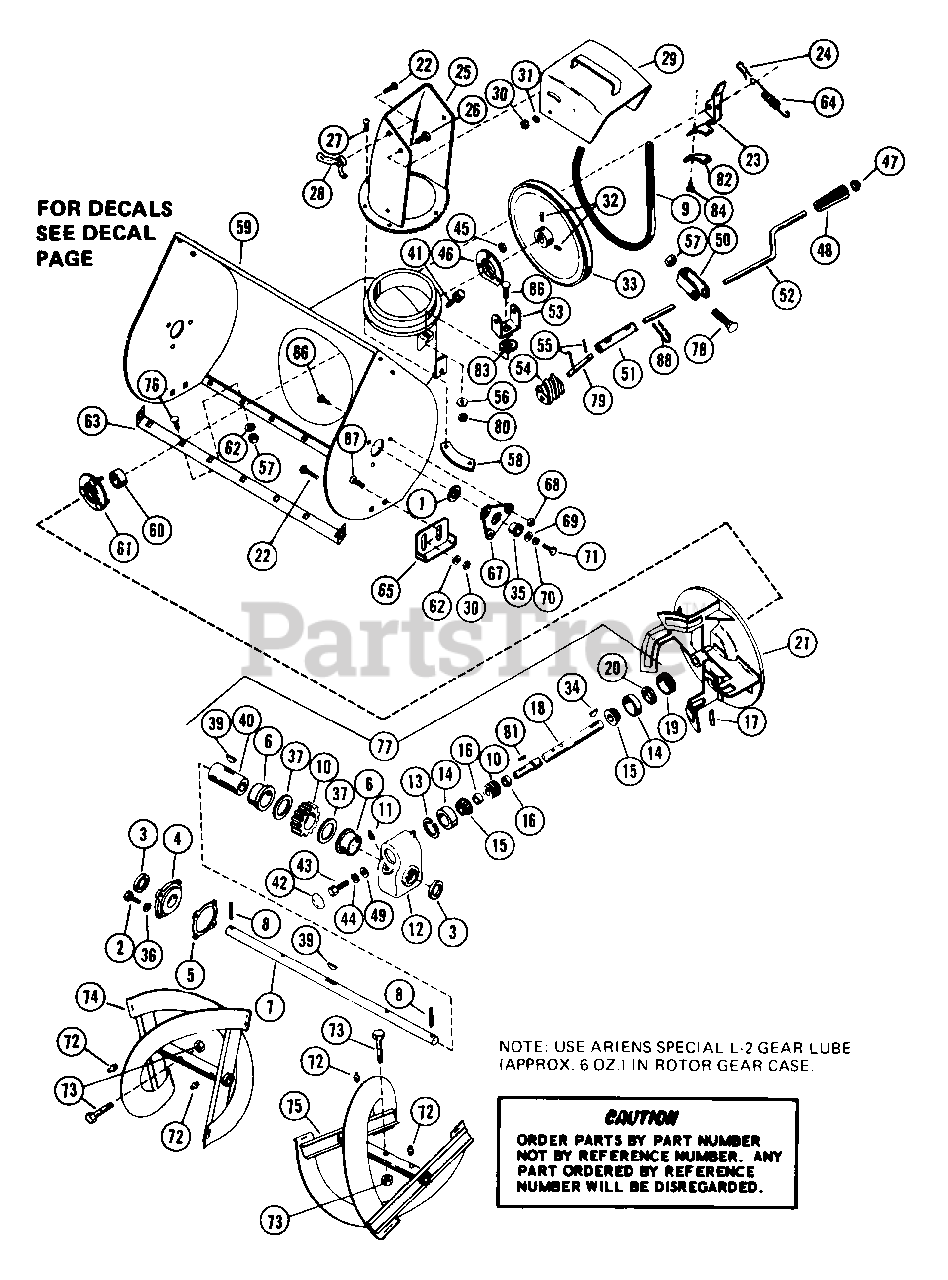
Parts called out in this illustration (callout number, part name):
1	WSHR-FL-STL 1.010X1.505X.062PL
2	BLT-HEX .25-20X.75 PL GR2
3	SEAL 1.625X2.125X.250
4	GEAR CASE COVER
6	BSHG-FLG .683X1.87X1.68X2.250
7	SHAFT, 32" RAKE - 1.00 DIA.
8	PIN-ROLL .188X1.50
10	WORM & GEAR SERVICE ASSEMBLY
11	PIPE PLUG
12	GEAR CASE - CAST IRON
13	RG-RTNG INT 1.781 HSG X.062
14	BRG-CUP 1.781X.475
15	BRG-CONE .750X.61
16	BSHG, SPCR .755X1.12X.50 PM
17	PIN-ROLL .313X1.75
18	SHAFT, WORM - 1.00 DIA.
19	ADJUSTMENT PLUG - 1" SHAFT
20	SEAL 1.000X1.312X.150
21	FAN, 12"
22	BLT-RDHDSQNK .38-16X.75 SHT PL
23	BRAKE ARM ASSEMBLY
24	PIN-COTR .12X1.0 PL
25	CHUTE - DISCHARGE
26	BLT-HEX .38-16X.75 PL GR2
27	SCR-TAP 10-24X.375 CRPH 1A
28	WING NUT
29	SERVICE DEFLECTOR ASSM
30	NUT-LK-CTR .375-16 GR A PL
31	WSHR-LK .375X.115 HVY PL
32	SCR-SET .32-18X.38 SKHCUPNL OH
33	PLY-? 9.0X.75
34	KEY-WDRF .188X.875X.375 SAE11
35	BSHG-FLG 1.000X1.12X.62X1.50BR
36	WSHR-LK-EXT. 250 ID
37	WSHR-FL-STL 1.625X2.500X.012
38	KEY-WDRF .25X.875X.375 SAE A
40	GEAR CASE SHAFT
41	BLT-SCRHFWH .38-16X.75 PL
42	DUST CAP
43	BLT-HEX .31-18X.75 PL GR2
44	WSHR-LK .312X.097 PL HVY
45	NUT-LK-CTR .250-20 PL
46	BEARING FLANGE
47	CAP, 3/8 ROD YWZC
49	WSHR-FL-STL .328X1.0X.094
50	BRACKET
51	SLEEVE CONNECTOR
52	CHUTE CONTROL CRANK
53	WORM CLEVIS
54	WORM GEAR
55	PIN-ROLL .125X.75
56	WSHR-LK .313X.062
57	NUT-LK .312-18 GR A PL
58	CHUTE CLAMP
59	32 IN BLOWER HOUSING ASSY
60	BRG-BALL .750X1.750X.50
61	BEARING FLANGE
62	WSHR-FL-STL .38X.875X.083 PL
63	SCRAPER BLADE
64	SG-TENS .062X.56X8.0 WLD 11
65	RUNNER
66	SCR-SLTR-SERNK .25-20X.62 PL
67	BEARING SUPPORT
68	NUT-LK-FLG .250-20 PL
69	WSHR-FL-STL .511X1.441X.125 PL
70	WSHR-LK .500X.151 HVY PL
71	BLT-HEX .50-13X1.00 PL GR2
72	SPIN DRIVE ZERK FITTING
73	SHEAR BOLT SERVICE ASSEMBLY
74	RAKE, RIGHT-32"(1ID X 15.75OD)
75	RAKE, LEFT-32"(1"ID X 15.75OD)
76	BLT-RDHDSQNK .312-18X.62 PL
77	GEAR CASE - CAST IRON
78	BLT-RDHDSQNK .31-18X1.38SHT PL
79	WORM SHAFT
80	NUT-HEX .312-18
81	KEY-SQ .188X1.0X.188 SAE 8630
82	BRAKE LINING
83	WSHR-LK-EXT .313X.030 PL
84	RVT-TBLR .187X.375 OH ST PL
86	BLT-RDHDSQNK .31-18X.75 GR5 PL
87	BLT-RDHDSQSHNK .38-16X1.00 PL
88	PIN-HAIR INT .09X.188 PL
